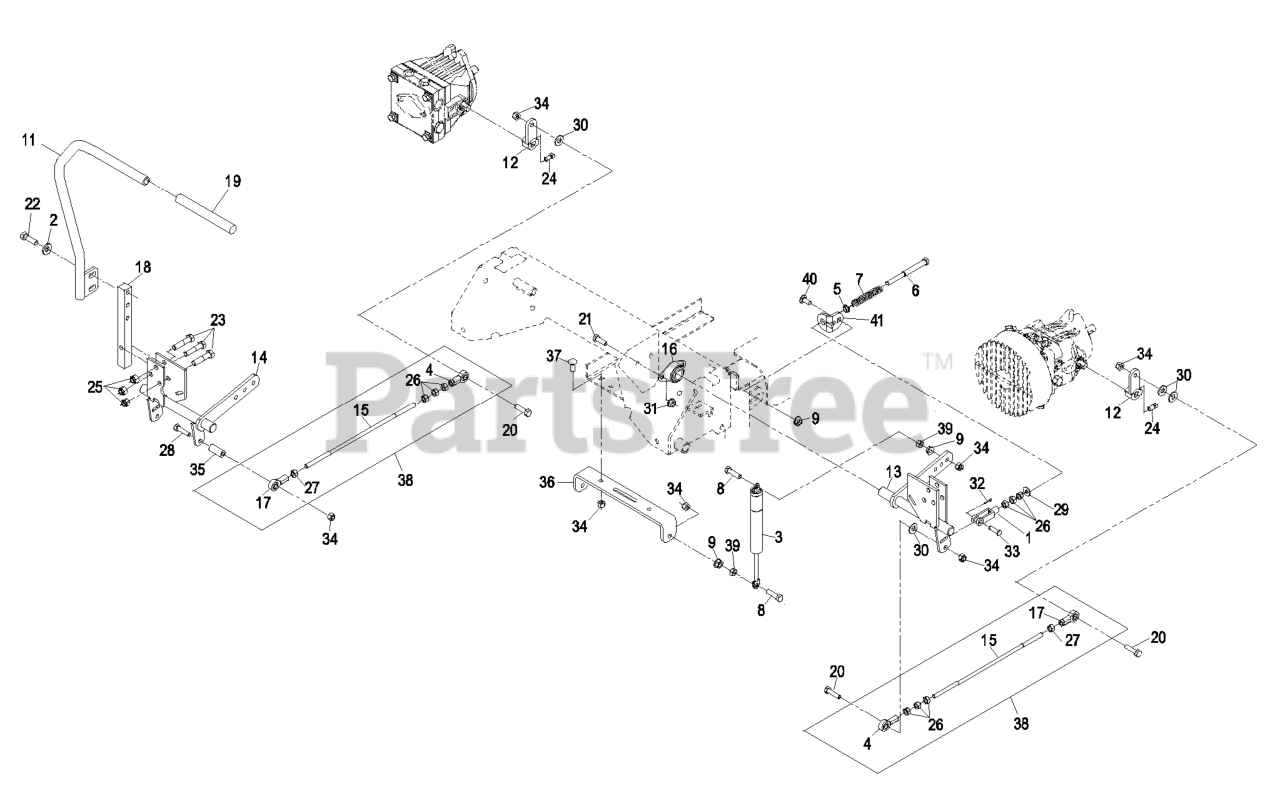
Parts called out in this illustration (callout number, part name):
1	YOKE-ADJUSTABLE
2	WASHER-BELLEVILLE
3	DAMPER-CONTROL, MOTION
4	BALLJOINT-RH
5	BUSHING-NYLON, FLANGED
6	BOLT-RETURN, NEUTRAL
7	SPRING-RETURN, NEUTRAL
8	SCREW-HH
11	ASM.RH LEVER/GRIP
12	ARM-CONTROL, PUMP
13	CONTROL-MOTION, LH
15	LINK-ROD, TRACKING
16	BEARING-FLANGE, SIDE
17	BALLJOINT-LH
18	ARM-SHAFT, CONTROL
19	GRIP,CONTROL LEVER
20	SCREW-HH
21	SCREW-HH
22	SCREW-HH
23	SCREW-HH
24	SCREW-SET
25	NUT-LOCK, NI
26	NUT-HEX
27	NUT
28	SCREW-HH
29	WASHER-FLAT
30	WASHER-FLAT
31	NUT-HHF, WHIZ
32	PIN-COTTER
33	PIN-CLEVIS
34	NUT-LOCK, NI
36	BRACKET-MOUNT, DAMPER
37	BOLT-CARR
38	TRACKING ROD ASM
39	NUT-HEX
40	SCREW-CARR
41	TAB-ADJUSTMENT
